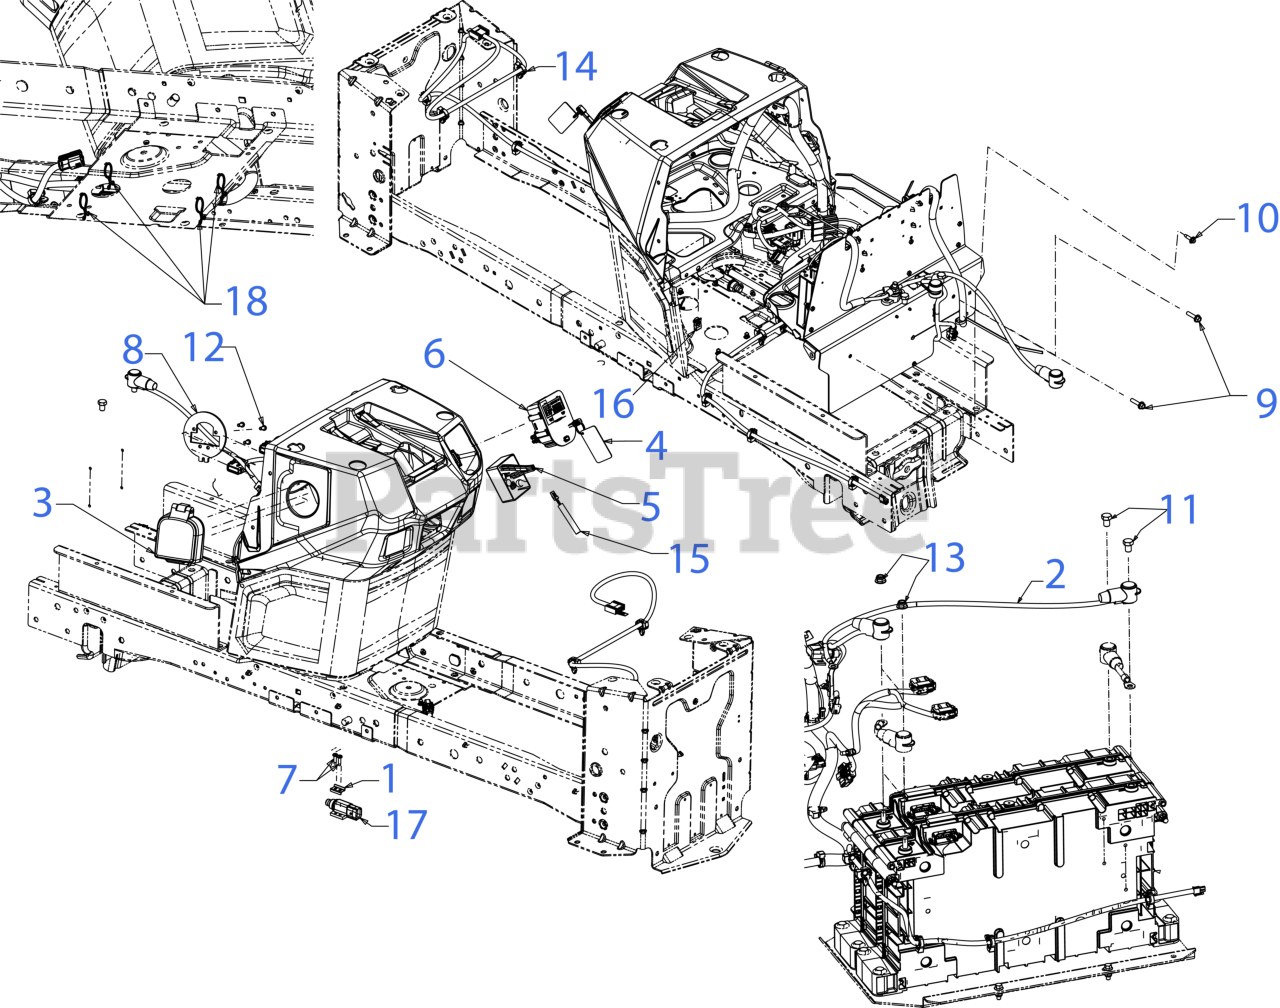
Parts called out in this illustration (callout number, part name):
1	PLATE-SWITCH
2	MOTOR CONTROL PANEL
3	LI-ION CHARGE PORT ASSEMBLY
4	MAGNETIC KEY
5	ELECTRIC MODULE
6	VCM SWITCH ASSEMBLY
7	SCREW #
8	CHARGE PORT MOUNTING PLATE
9	SCREW 1/4-20 x 1.0
10	SCREW 1/4-10 x .750
11	SCREW 3/8-24 x .50" GR5 STD
12	SCREW #12-16 x .625
13	FLANGE LOCK NUT 5/16-18
14	HARNESS (VCM HPD BATTERY)
15	HARNESS(6.49K 13.3K)
16	U-CLIP NUT
17	SEALED PLUNGER SWITCH
18	TWIST LOCK CLIP
